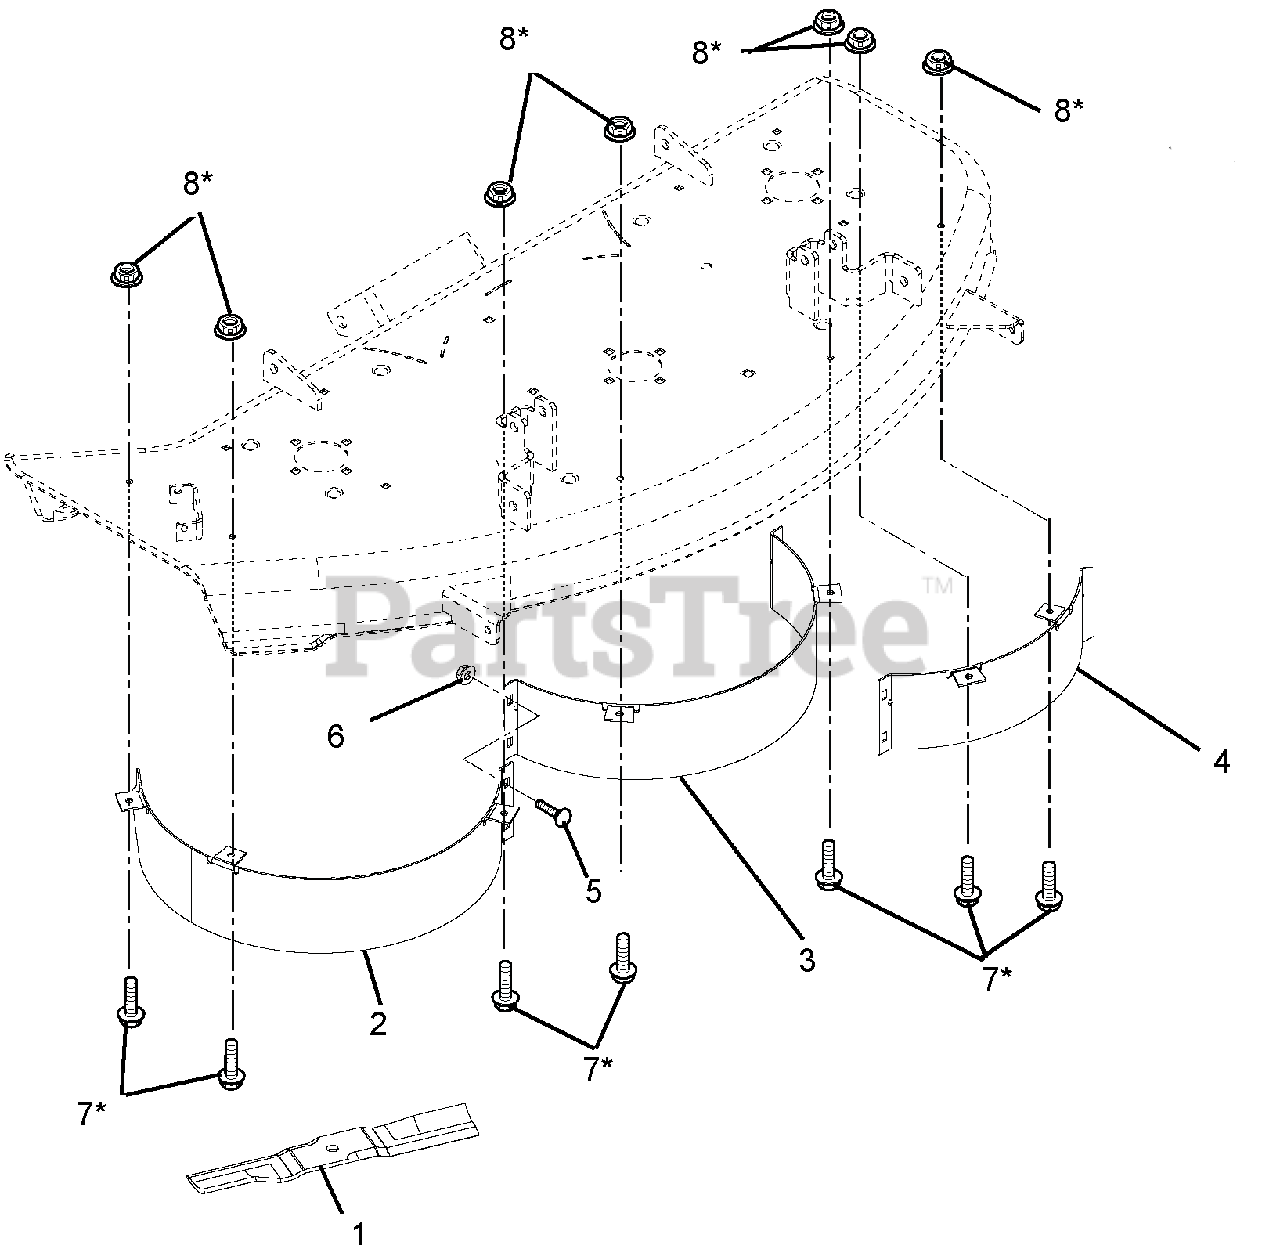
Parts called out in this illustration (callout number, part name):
1	BLD,MULCHING 50" MWR
2	MULCH BAFFLE, CHUTE
3	MULCH BAFFLE,CENTER
4	MULCH BAFFLE, LEFT
5	@BLT-RDHDSQNK .31-18X1.00 G5YZ
6	@NUT-LK-TOP-FLG .31-18 YWZC
7	@BLT-HEX .31-18X.75 GR5 YWZC
8	@NUT-SPNLK-FLG .312-18 YWZC
